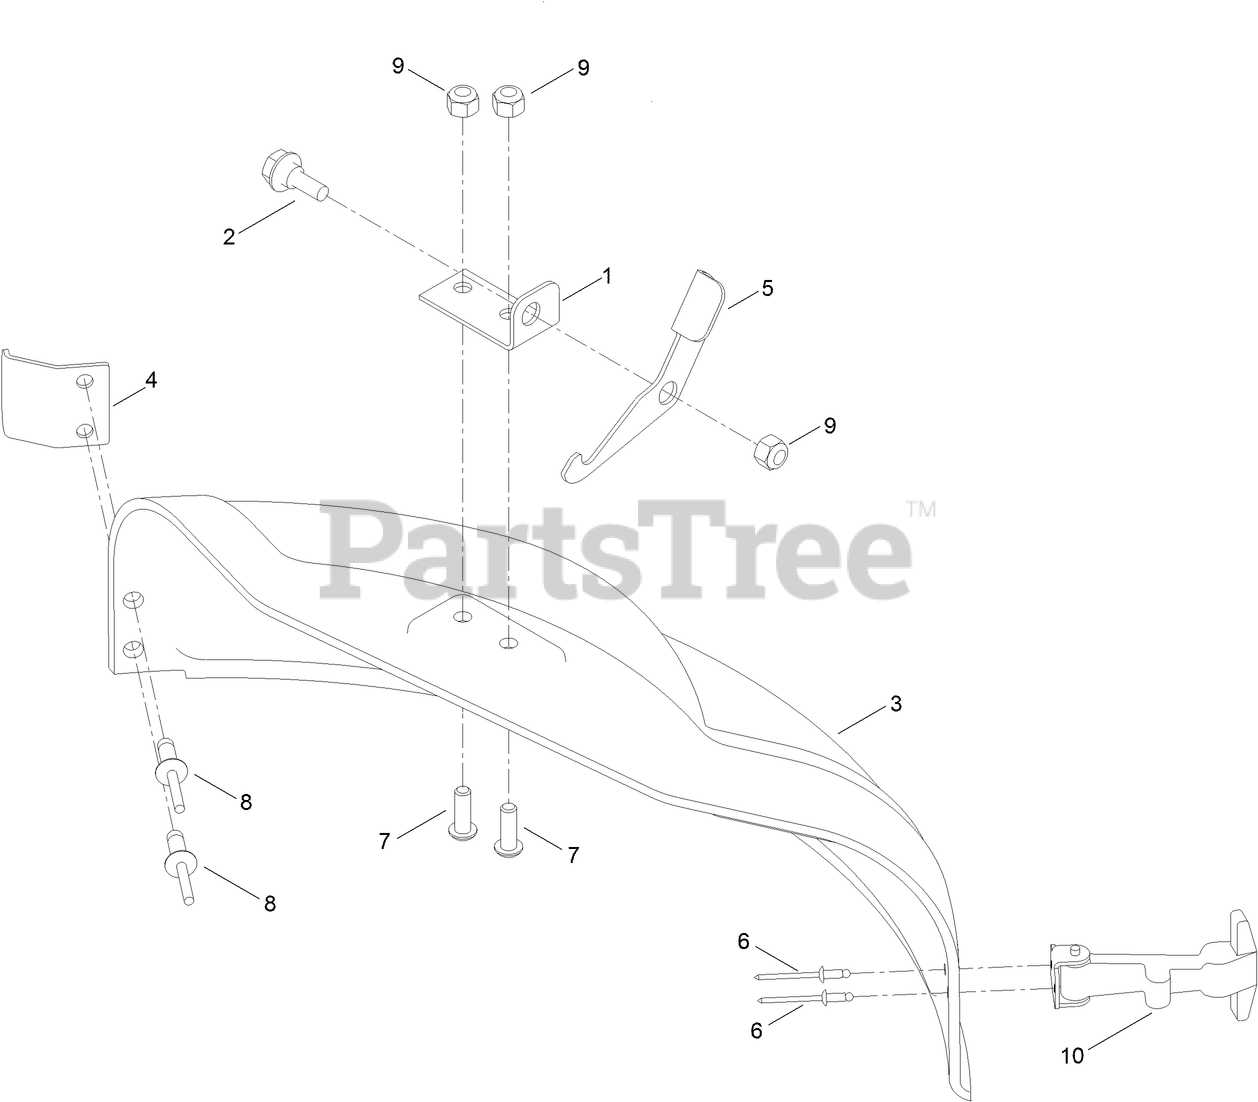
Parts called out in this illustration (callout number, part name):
1	PLATE-PIVOT
3	PLUG-MULCH, 42 INCH
4	BRACKET-ELBOW
6	RIVET-POP
7	SCREW-HSBH
8	RIVET-BLIND
9	NUT-HEX
10	HANDLE ASM
